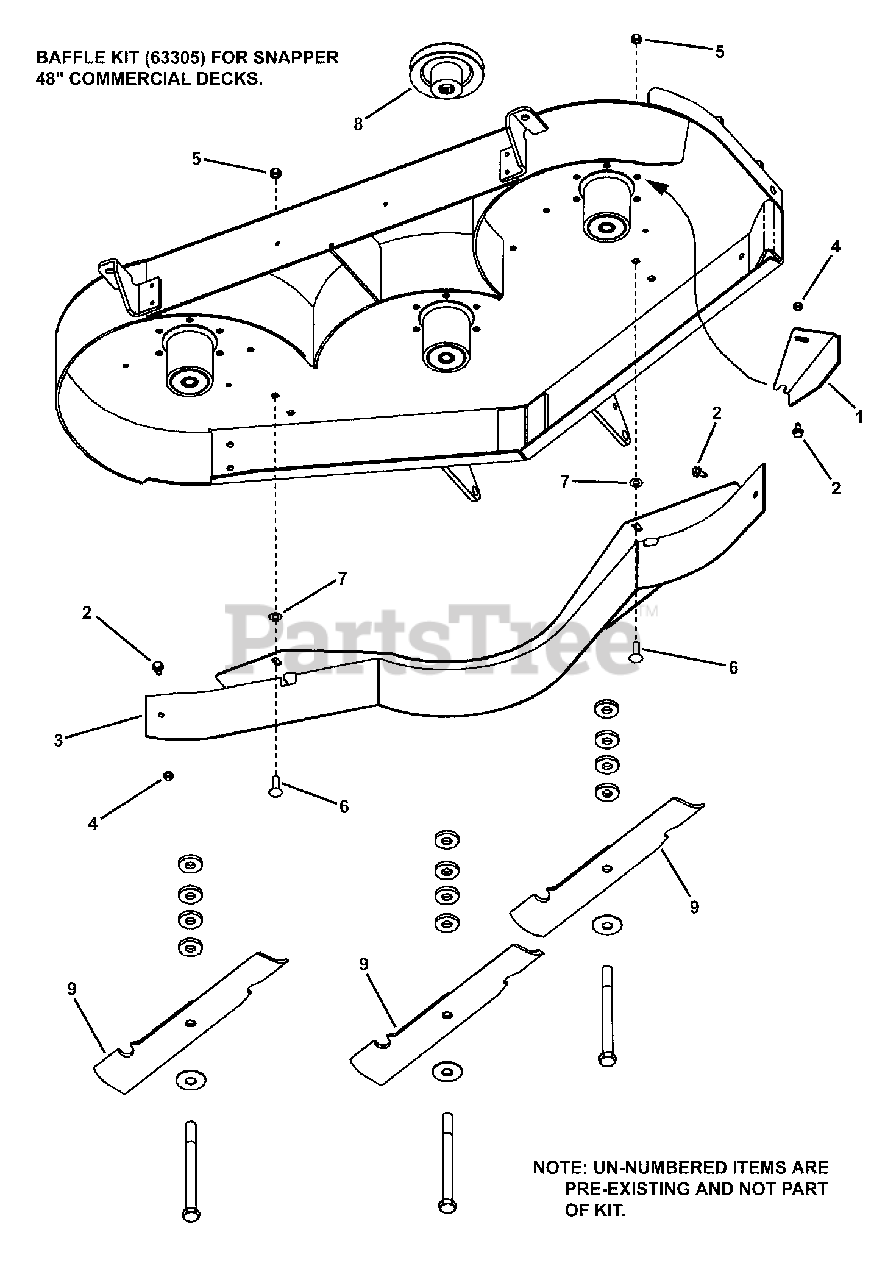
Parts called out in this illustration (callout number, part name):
1	BAFFLE, Discharge, 48" Deck
2	SCREW, 5/16-18 x 5/8" Hex Washer Self-Tap
3	WELDMENT, Baffle, 48" Deck
4	NUT, 5/16-18 Hex Center Lock, GR5 or B
5	NUT, 3/8-16 Hex Center Lock, GR5 or B
6	BOLT, 3/8-16 x 1-1/4" Square Neck Carriage, GR5
7	RETAINER, 3/8" Bolt
8	PULLEY, Driven 48" Deck
9	BLADE, 16.5"
